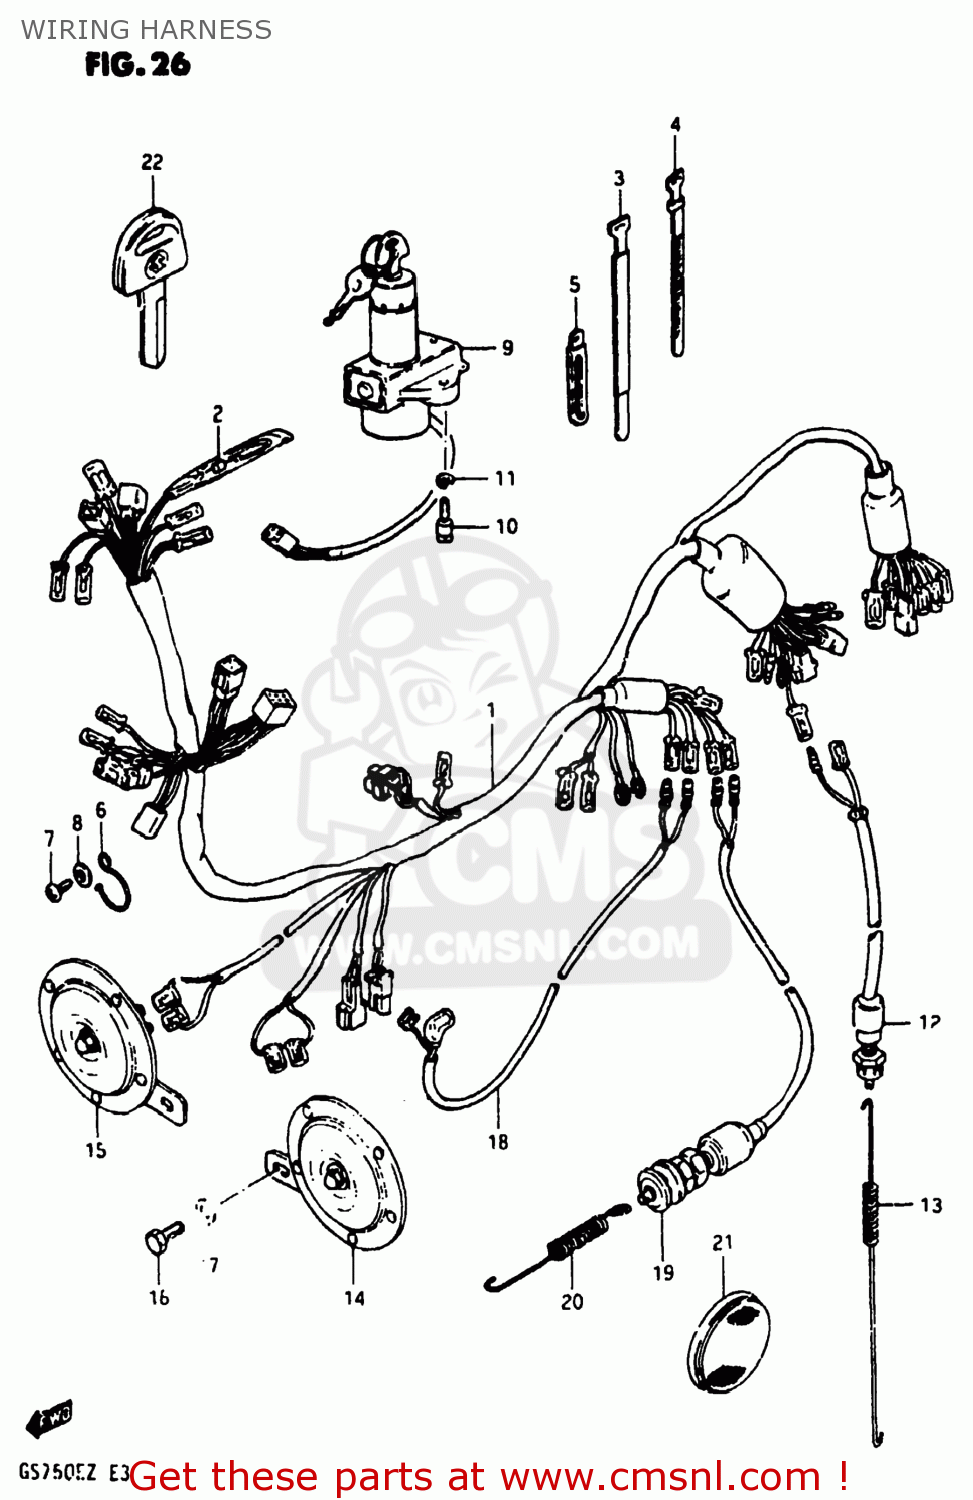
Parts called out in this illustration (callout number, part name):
1	HARNESS,WIRING
2	DIODE
3	CLAMP
4	CLAMP(L:120)
5	CLAMP
6	GUIDE,WIRING HARNESS
7	SCREW 6X12
8	WASHER
9	SWITCH ASSY,IGNITION
10	BOLT
11	LOCK WASHER
12	SWITCH ASSEMBLY,STOP LAMP
13	SPRING
14	HORN ASSEMBLY,LOW PITCH
15	HORN ASSEMBLY,HIGH PITCH
16	BOLT 8X12
17	WASHER
18	WIRE,OIL PRESSURE LEAD
19	SWITCH ASSEMBLY,SIDE STAND
20	SPRING
21	REFLEX REFLECTOR,RR
22	KEY,BLANK
